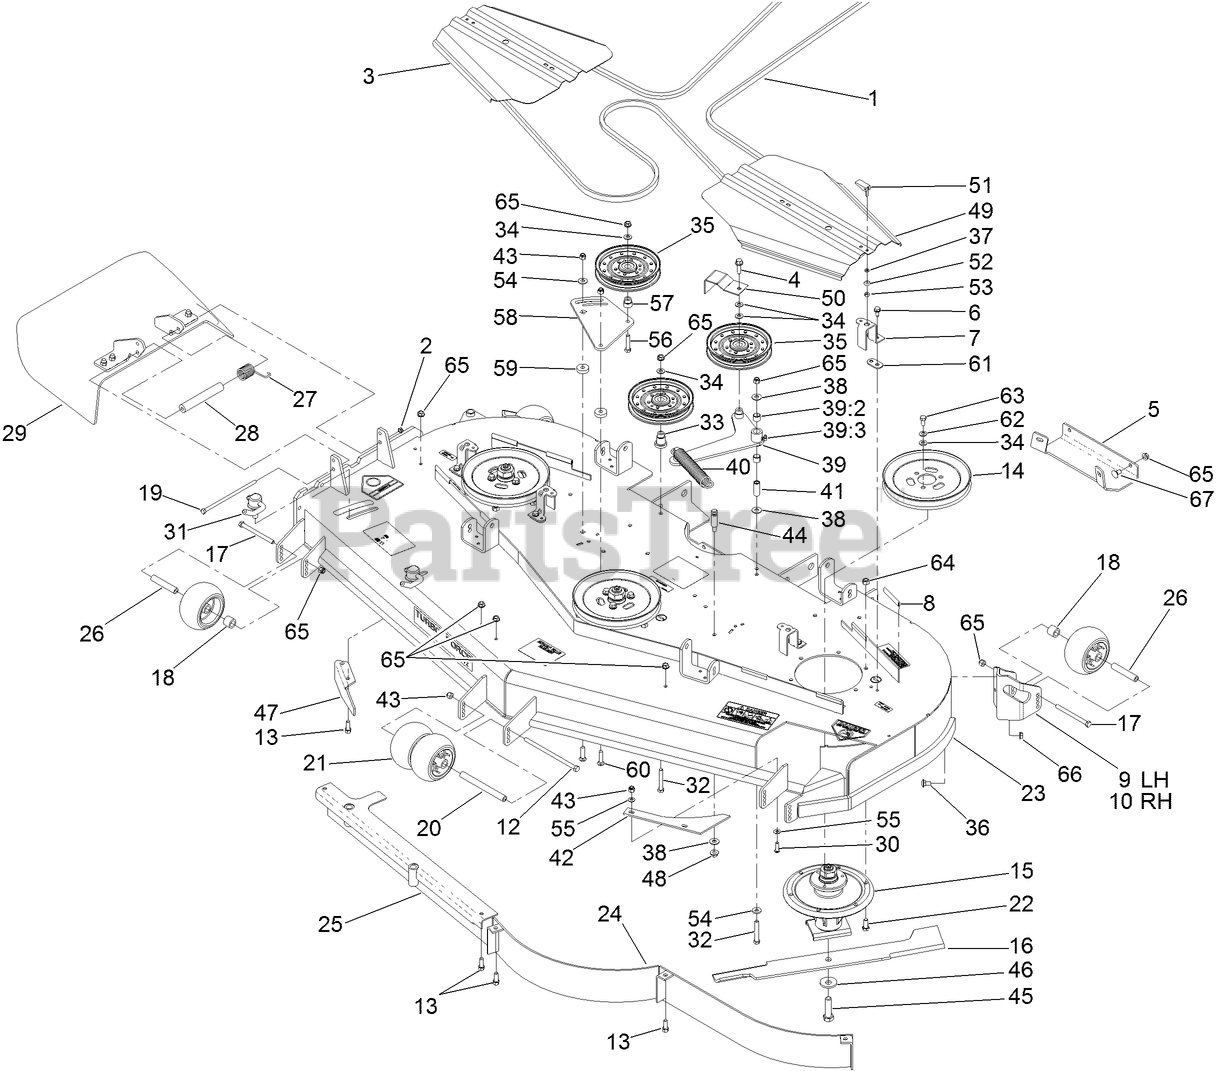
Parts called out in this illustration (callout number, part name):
2	NUT-LOCK, NI
3	COVER-BELT, RH
4	SCREW-HHF
5	Plate-Skid
6	SCREW-HWHTF
7	BRACKET-COVER
8	STRIP-SEAL
9	MOUNT-WHEEL, LH
10	MOUNT-WHEEL, RH
12	SCREW-HH
13	SCREW-HWH
14	Pulley
15	SPINDLE ASM
16	BLADE-HI FLOW, 24.5 INCH
17	SCREW-HH
18	TUBE-SPACER
19	SCREW-HH
20	SPACER-WHEEL
21	ROLLER-SCALP, ANTI
22	SCREW-HH
23	DECK DECAL ASM
26	TUBE-SPANNER
27	SPRING-TORSION
28	SPACER
29	RUBBER DEFLECTOR ASM
30	SCREW-HSBH
31	LEVER ASM
32	SCREW-HH
33	MOUNT-PULLEY
34	WASHER-FLAT
35	IDLER-PULLEY, FLAT
36	SCREW-CARR
37	WASHER
38	WASHER-FLAT
39	DECK IDLER ARM ASM
39:2	SLEEVE-BEARING
39:3	FITTING-GREASE, 90 DEG
40	SPRING-EXTENSION
41	BUSHING
42	PLATE-TURBO
43	NUT-LOCK, NI
44	PIN-THREADED, SPRING ANCHOR
45	SCREW-BLADE
46	Washer-Blade Bolt, Heavy
47	BAFFLE-DISCHARGE
48	NUT-HF
49	COVER-BELT, LH
50	GUIDE-BELT
51	HANDLE-LATCH, SWELL
52	BUSHING-LATCH, SWELL
53	NUT-LOCK, HH
54	WASHER-BELLEVILLE
55	WASHER-SPRING
56	SCREW-HH
57	BUSHING-IDLER
58	Plate-Idler
59	Spacer
60	SCREW-CARR
61	SPACER-BELT COVER
62	WASHER-BELLEVILLE
63	SCREW-HH
64	NUT-LOCK, NI
65	NUT-HF, NI
66	NUT-LOCK, NI
67	SCREW-CARR
